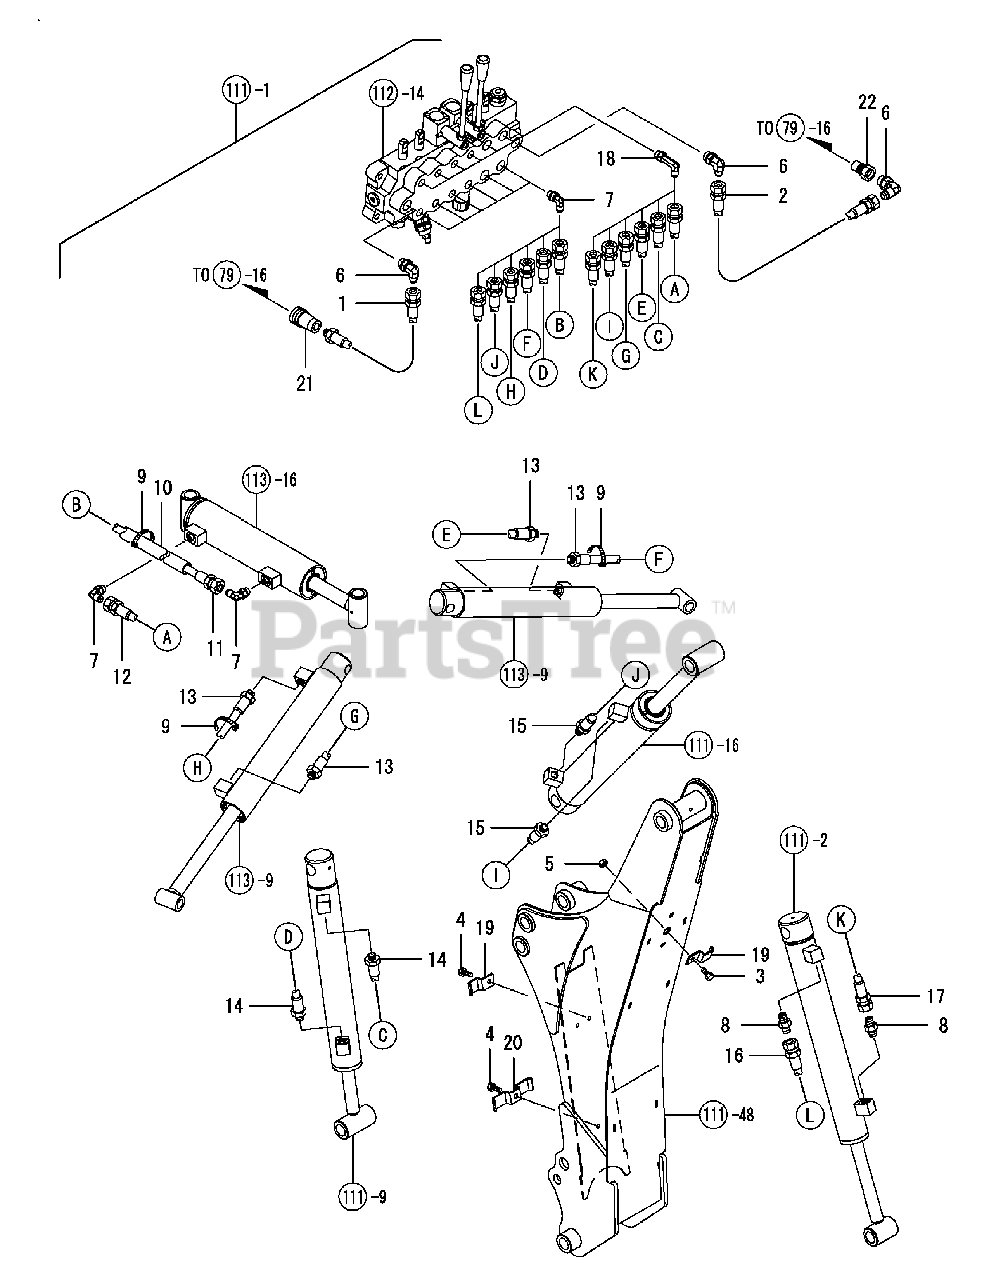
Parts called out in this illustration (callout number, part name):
1	HYD HOSE 3/8X27
2	HYD HOSE 3/8X40
3	BOLT, HEX 5X31
4	BOLT, THO 31X75
5	NUT, LOCK NC 31
6	ADAPTER, UNION
7	ADAPTER, FLARE
8	ADAPTER, FLARE
9	PLASTC TIE-BLACK
